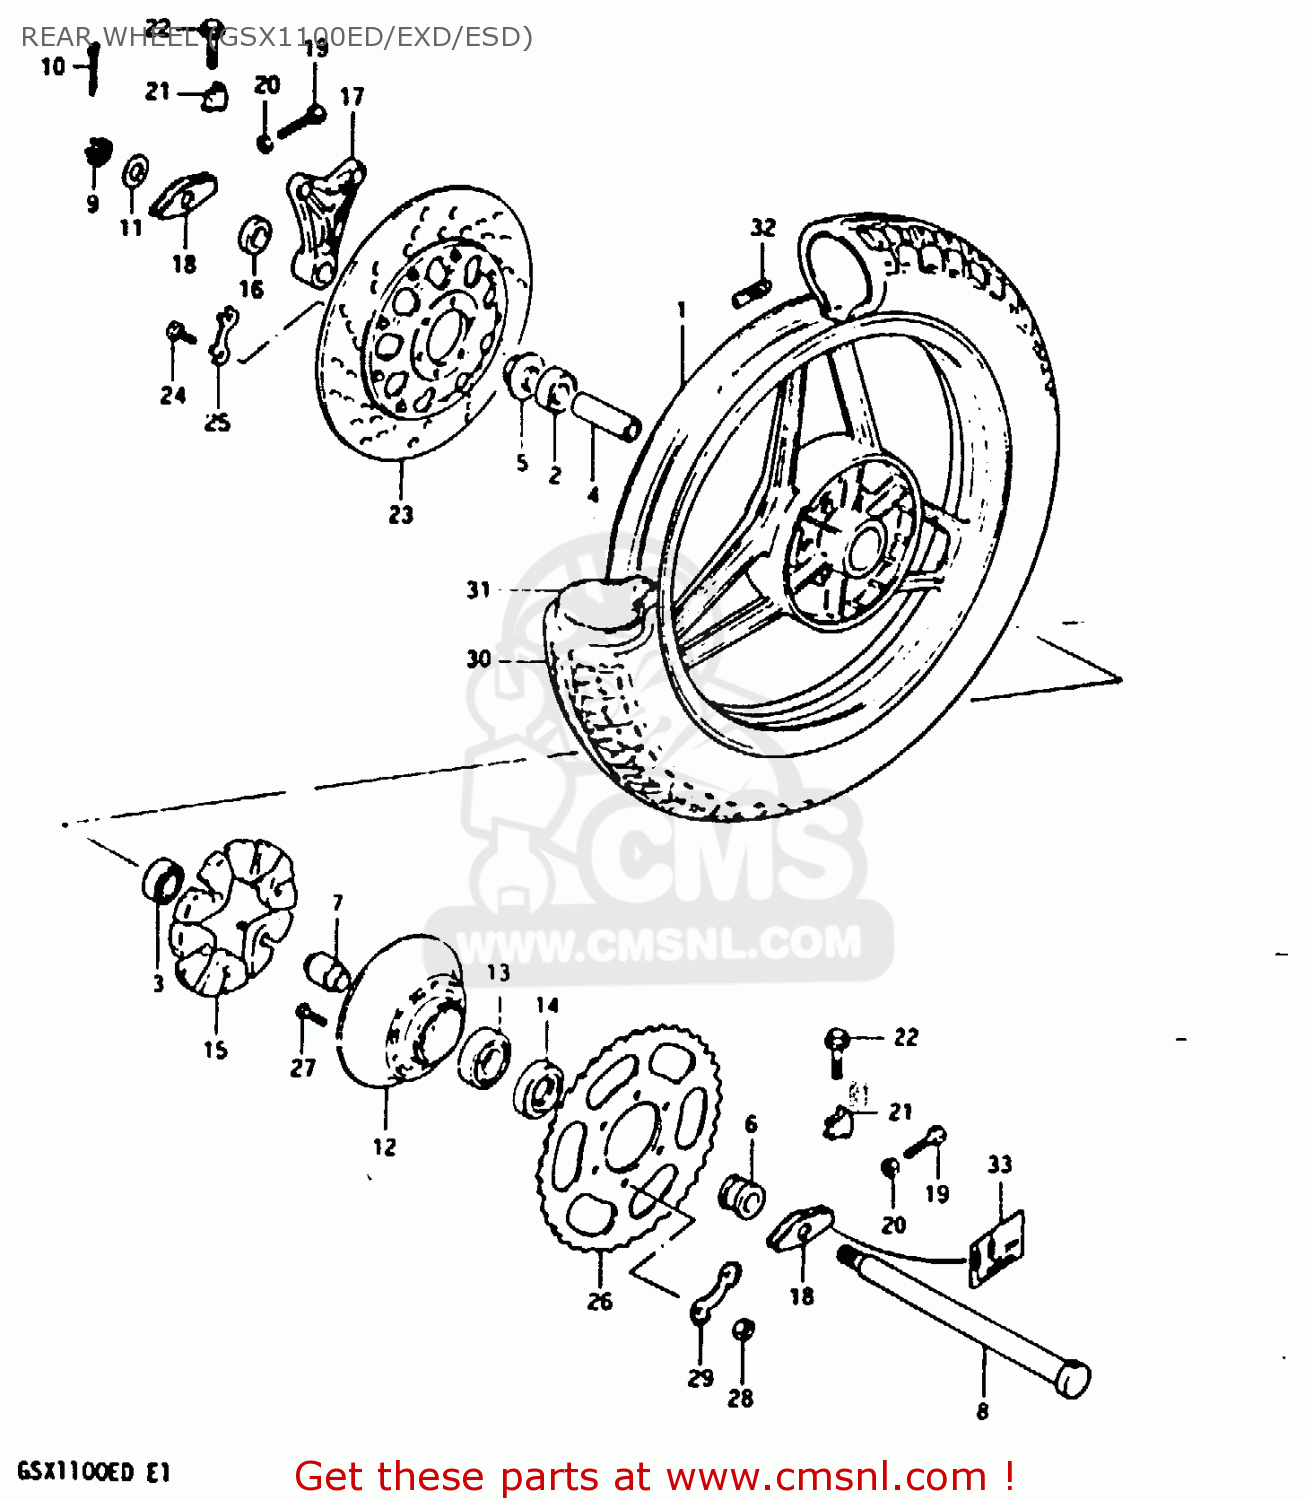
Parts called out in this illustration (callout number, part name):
1	CASTING WHEEL,REAR 2.50
2	BEARING WHEEL REAR(20X47X14)
3	BEARING, LH
4	SPACER(20.5X28X88)
5	SPACER,REAR AXLE
6	SPACER(20X33X28.3)
7	SPACER,REAR HUB BEARING
8	AXLE,REAR
9	NUT 18MM
10	PIN,COTTER
11	WASHER(19X34X4)
12	DRUM,REAR SPROCKET MOUNT
13	BEARING
14	SEAL,OIL(33X62X7)
15	ABSORBER,REAR HUB SHOCK
16	SPACER(20X38X12)
17	BRACKET,RR,CALIPER
18	ADJUSTER,CHAIN
19	BOLT 8X35
20	NUT
21	SUPPORTER,CHAIN ADJUST
22	BOLT
23	DISC,RR BRAKE
24	BOLT(8X30)
25	WASHER
26	SPROCKET,REAR
27	BOLT
28	NUT
29	WASHER
30	TIRE (4.50V17)
31	TUBE ASSEMBLY,WHEEL,INNER
32	BALANCER,WHEEL
33	LABEL,CHAIN WEAR INDICATOR
